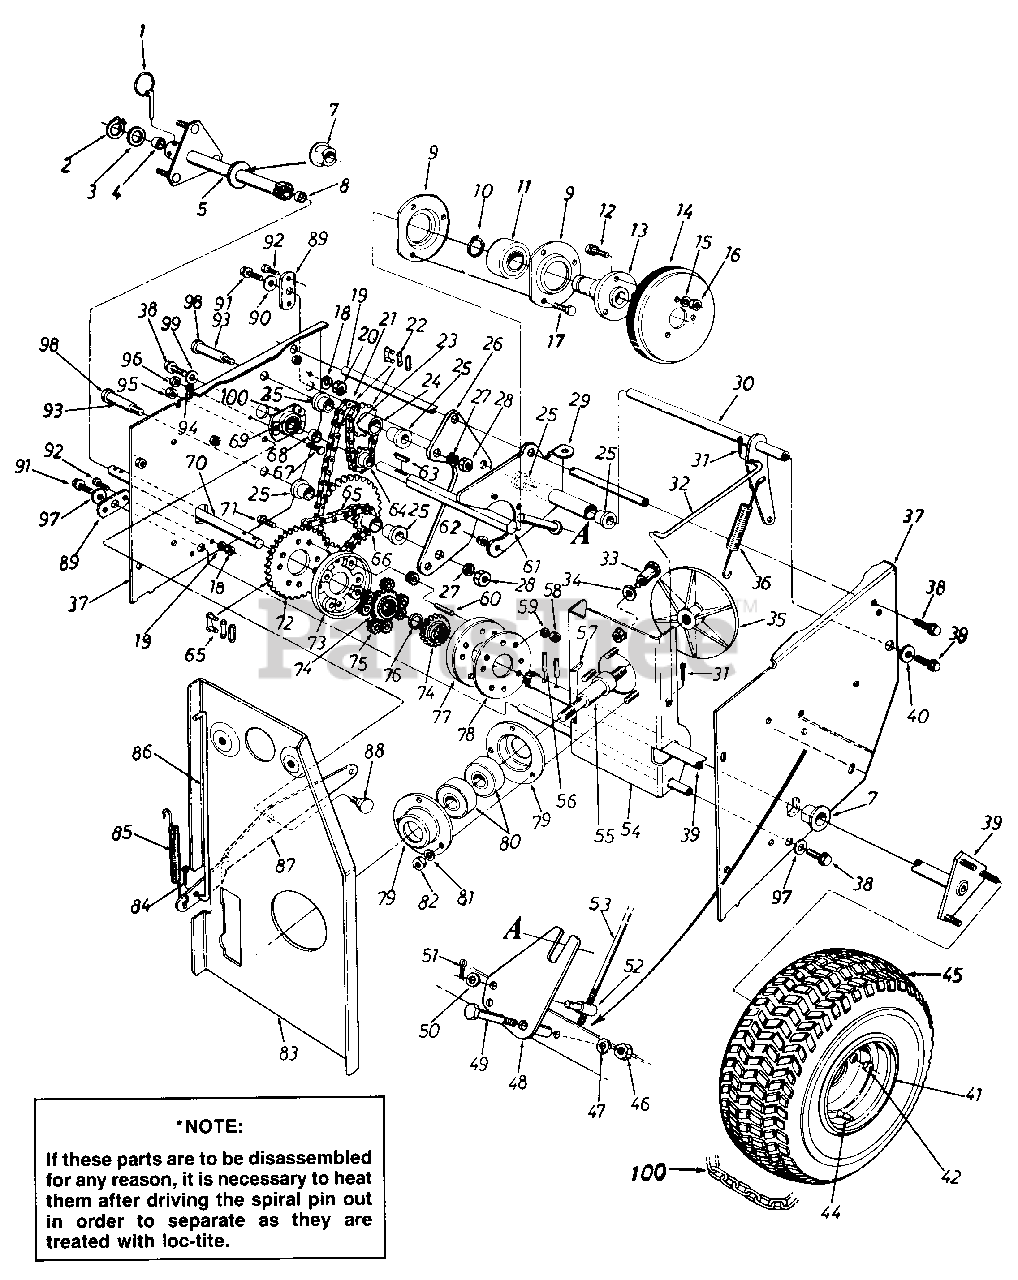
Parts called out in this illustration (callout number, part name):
1	Klick Pin 1/4'/ Dia. x 1.75"
2	Snap Ring .625" Shaft
3	Fl-Wash. .62" I.D. x 1.25"
4	Sleeve Brg.
5	Differential Tubing Ass'y.-R.H.
7	Flange Brg. w/Flats 1" I.D.
8	Sleeve Brg.
9	Bearing Housing
10	Snap Ring-1.00" Dia.
11	Ball Brg. .25MM x 52MM x 15MM Thk.
12	Hex Sems Bolt 5/16-18 x .75" Lg.*
13	Friction Wheel Adapter
14	Friction Wheel Ass'y.
15	L-Wash. 5/16" I.D.
16	Hex Nut 5/16-18 Thd.
17	Hex Bolt 1/4-28 x .62" Lg.
18	L-Wash. 1/4" I.D.
19	Sliding Support Axle
20	Hex Nut 1/4-20 Thd.
21	#41 Chain-1/2" Pitch x 43 Links
22	Master Link
23	#41 Chain-1/2" Pitch x 19 Links
24	9 and 14 Teeth Sprocket Hub Ass'y.
25	Flange Brg. .630" I.D.
28	Hex L-Jam Nut 3/8-24 Thd.
29	Sliding Brkt. Ass'y.
30	Drive Clutch Brkt. Ass'y.
31	Inter. Cot. Pin 5/16" Dia.
32	Drive Clutch Rod 7.38" Lg.
33	Shld. Bolt
34	Bell-Wash. .44" I.D. x .88"
35	Aluminum Drive Plate
36	Extension Spring 4.31" Lg.
37	Frame Ass'y.
38	Hex L-Bolt 5/16-18 x .62"
39	Differential Shaft Ass'y.
40	Fl-Wash. .345" I.D. x .75"
41	Rim Only-16"
42	Cone Nut 3/8-24 Thd.
44	Tubeless Air Valve
45	Wheel Ass'y. Comp. 16 x 6.5
46	Hex Jam Nut 3/8-16 Thd.
47	L-Wash. 3/8" I.D.
50	Fl-Wash. .344" I.D. x .62"
51	Cotter Pin 3132" Dia. x .75"*
52	Adjustment Ferrule
53	Shifting Rod
56	H-Spring Pin Spiral 3/16" Dia. x 1.25" Lg.
57	#61 Hi-Pro Key 3/16 x 5/8" Dia.
58	Hex Nut 1/4-28 Thd.
59	L-Wash. 1/4" I.D.*
60	Differential Pin
61	Hex Shaft
62	Hex L-Nut 1/4-28 Thd.
63	#9 Hi-Pro Key 3/32 x 5/8" Dia.
64	8 Teeth Sprocket
65	#420 Chain-.50 Pitch x 37 Links
66	9 and 32 Teeth Sprocket Hub Ass'y.
67	Hex Bolt 1/4-20 x .62" Lg.*
68	Spacer .51 I.D. x .69" O.D.
69	Ball Bearing
70	Differential Connecting Shaft
71	Hex Bolt 1/4-28 x 1.75" Lg.*
72	28 Teeth Sprocket
73	Differential Housing
74	20 Tooth Spur Gear
75	9 Tooth Spur Gear
76	Fl-Wash. .62n I.D. x 1.25'
77	Differential Housing
78	Differential Hsg. Support Plate
79	Bearing Housing
80	Ball Brg. .787" I.D. x 1.85"
81	L-Wash. 5/16" I.D.*
82	Hex Nut 5/16-18 Thd.*
83	Engine Brkt. Ass'y.
84	Inter. Cotter Pin 5/16" Dia.
85	Extension Spring 3.18" Lg.
86	Auger Clutch Rod .31" Dia. x 1 0.62n Lg.
87	Auger Clutch Brkt.
88	Shld. Bolt .625" Dia. x .170"
89	Pivot Axle Brkt.
90	Fl-Wash. .345" I.D. x .75
91	Hex L-Bolt 5/16-18 x .62"
92	Hex Bolt 1/4-20 x .62" Lg.*
93	Sprocket Hub Tubing 1.88n
94	L-Wash. 1/4" I.D.*
95	Hex Cent. L-Nut 3/8-16 Thd.
96	Hex Nut 1/4-20 Thd.*
97	Fl-Wash. .344" I.D. x .875"
98	Hex Bolt 3/8-24 x 2.75n Lg.*
99	Bell-Wash. .345" I.D. x .88"
100	Tire Chain
